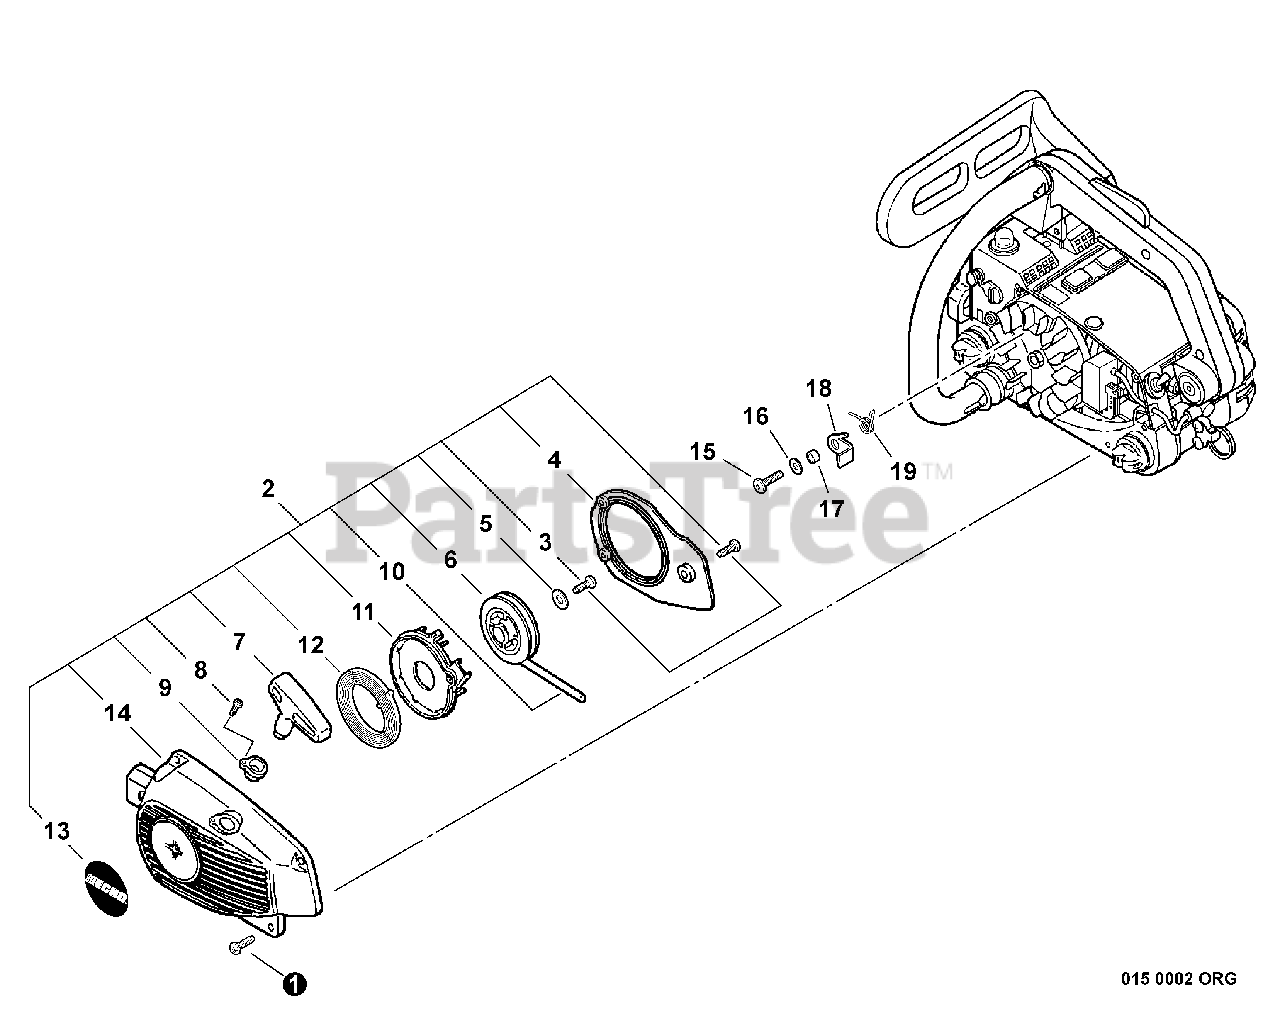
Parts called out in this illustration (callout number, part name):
1	SCREW - 4X16
2	STARTER ASSY
3	SCREW - 4X14
6	REEL, ROPE
7	GRIP, STARTER
8	SCREW - 3X14
9	GUIDE, ROPE
10	ROPE, STARTER - 3X850
11	PLATE, STARTER
12	REWIND SPRING ASSY
13	LABEL - ECHO
14	CASE, STARTER - ORANGE
15	SCREW - 5X12
16	WASHER - 5
18	PAWL, STARTER
19	SPRING, RETURN
